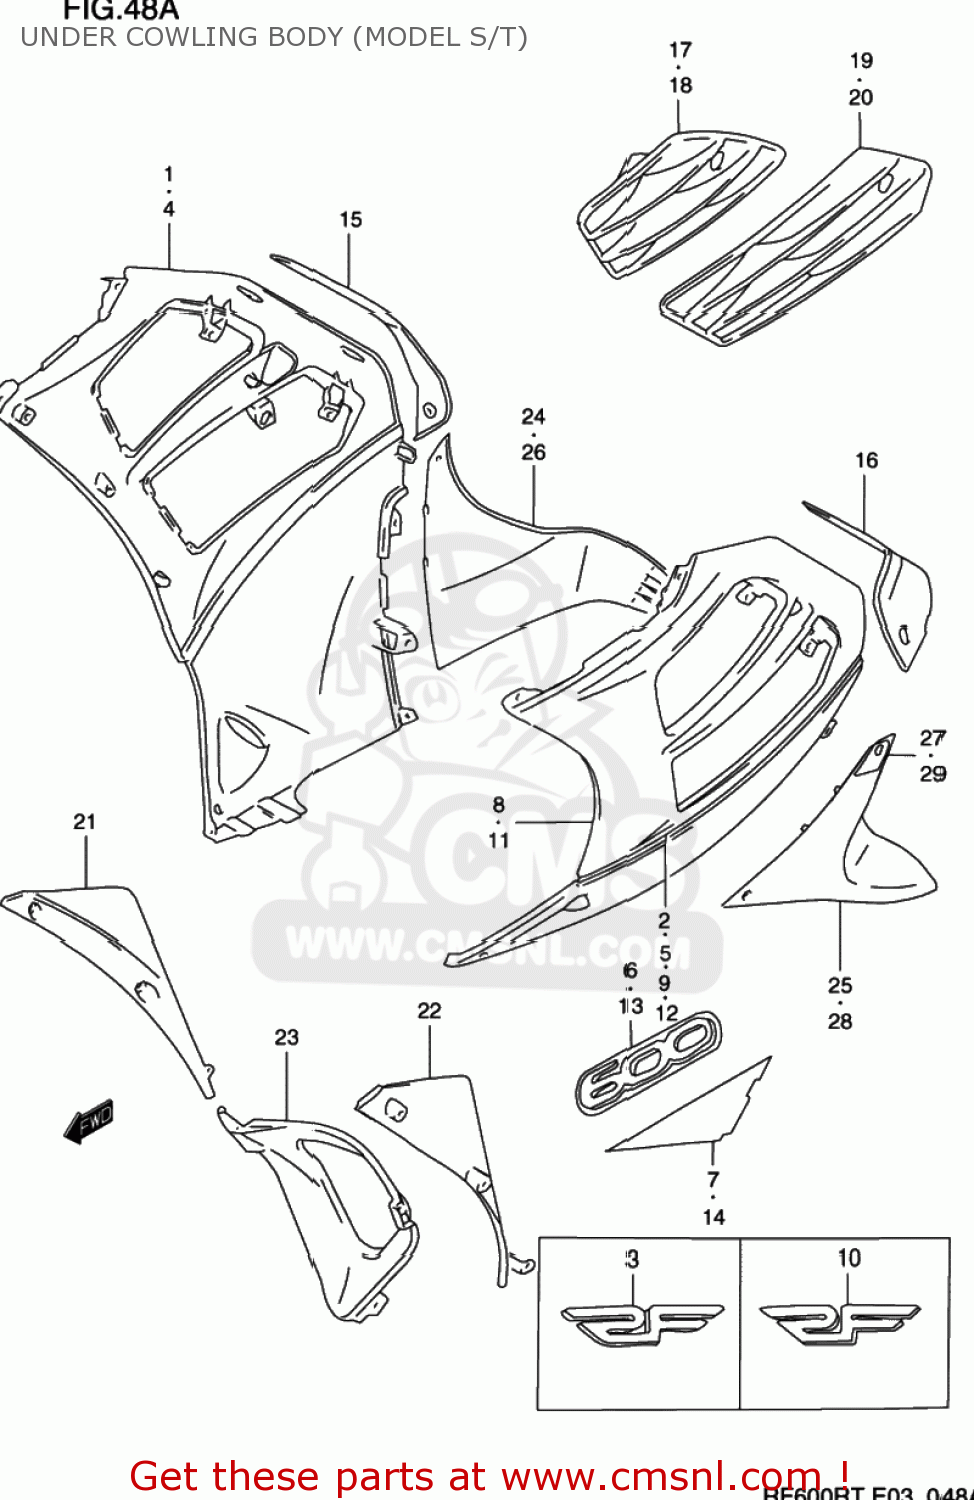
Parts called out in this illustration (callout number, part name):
1	COWLING ASSY,UNDER,R
2	TAPE,UNDER COWL,R
3	EMBLEM,COWLING UNDER,R
4	COWLING ASSY,UNDER,R
5	TAPE,UNDER COWL,R
6	EMBLEM,COWLING,UNDER
7	TAPE,COWL UNDER LWR,R
8	COWLING ASSY,UNDER,L
9	TAPE,UNDER COWL,L
10	EMBLEM,COWLING UNDER,L
11	COWLING ASSY,UNDER,L
12	TAPE,UNDER COWL,L(BLACK)
13	EMBLEM,COWLING,UNDER
14	TAPE,COWL UNDER LWR,L
15	PANEL,UNDER,R
16	PANEL,UNDER,L
17	COVER,UNDER COWL UPR,R
18	COVER,UNDER COWL UPR,L
19	COVER COMP,UNDER COWLING
20	COVER,UNDER COWL LWR,L
21	COWLING,UNDER INNER,R
22	COWLING,UNDER INNER,L
23	COWLING,UNDER CTR
24	COWLING,UNDER RR,R
25	COWLING COMP,UNDER,REAR
26	COWLING COMP,UNDER,REAR
27	TAPE,COWLING,UNDER,REAR
28	COWLING,UNDER RR,L
29	TAPE,COWLING,UNDER,REAR
